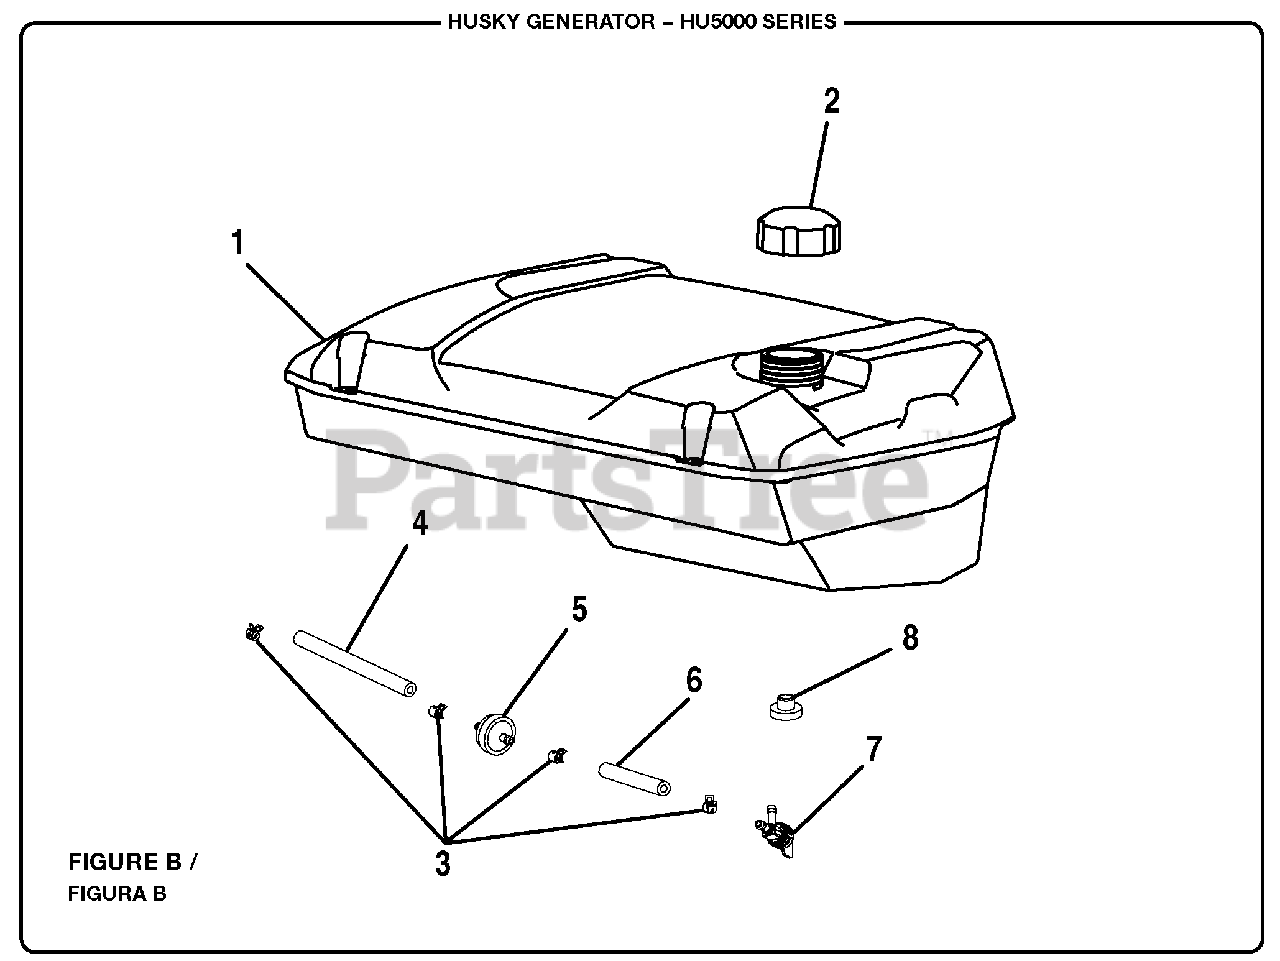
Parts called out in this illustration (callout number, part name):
1	Fuel Tank
2	Fuel Tank Cap
3	Fuel Line Clamp (1/2 in.)
4	Fuel Line (6.4 mm x 208 mm)
5	Fuel Filter
6	Fuel Line (6.4 mm x 105 mm)
7	Fuel Shut off Valve
8	Fuel Line Bushing
